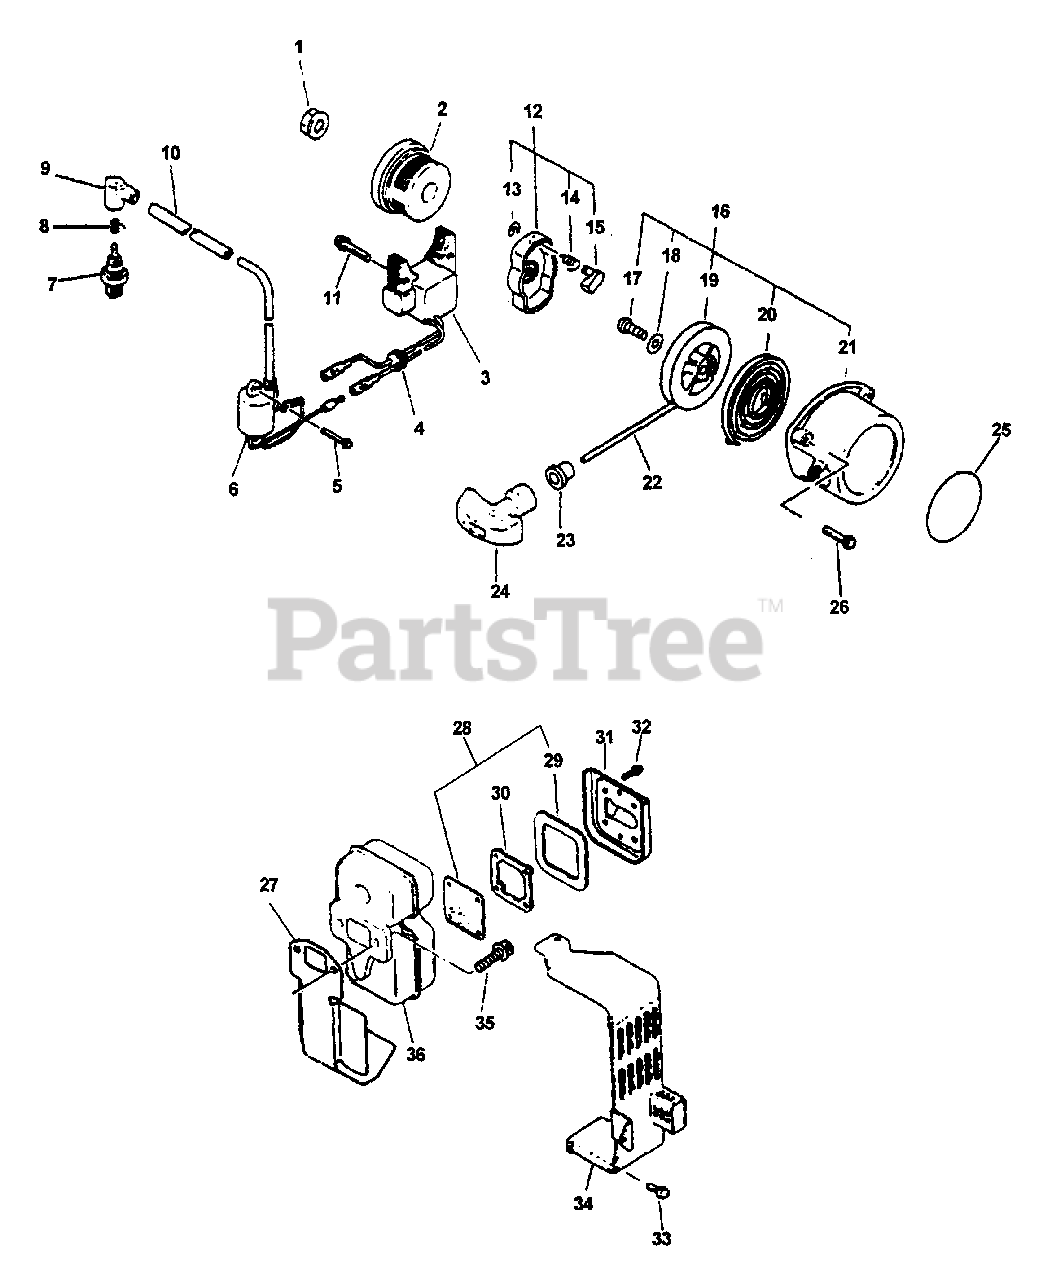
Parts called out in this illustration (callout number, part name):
1	NUT, FLANGE 10×1.25
2	FLYWHEEL
3	COIL, IGNITION
5	SCREW 4×25
6	COIL, IGNITION
7	SPARK PLUG - BM6A
8	TERMINAL, SPARK PLUG CAP
9	CAP, SPARK PLUG
10	TUBE, INSULATOR
11	SCREW 5×25
12	PAWL CATCHER ASSY
13	E-RING 4
14	SPRING, RETURN
15	PAWL, STARTER
16	STARTER ASSY
19	REEL, ROPE
20	SPRING, RECOIL
21	CASE, RECOIL STARTER
23	GUIDE, ROPE
24	GRIP, STARTER
25	LABEL, ECHO
26	SCREW 5×16
27	GASKET, EXHAUST
28	SCREEN KIT
29	GASKET, EXHAUST
30	SEAT, SCREEN
31	GUIDE, EXHAUST
32	SCREW 4×14
33	SCREW 5×14
34	COVER, MUFFLER
35	BOLT 6×20
